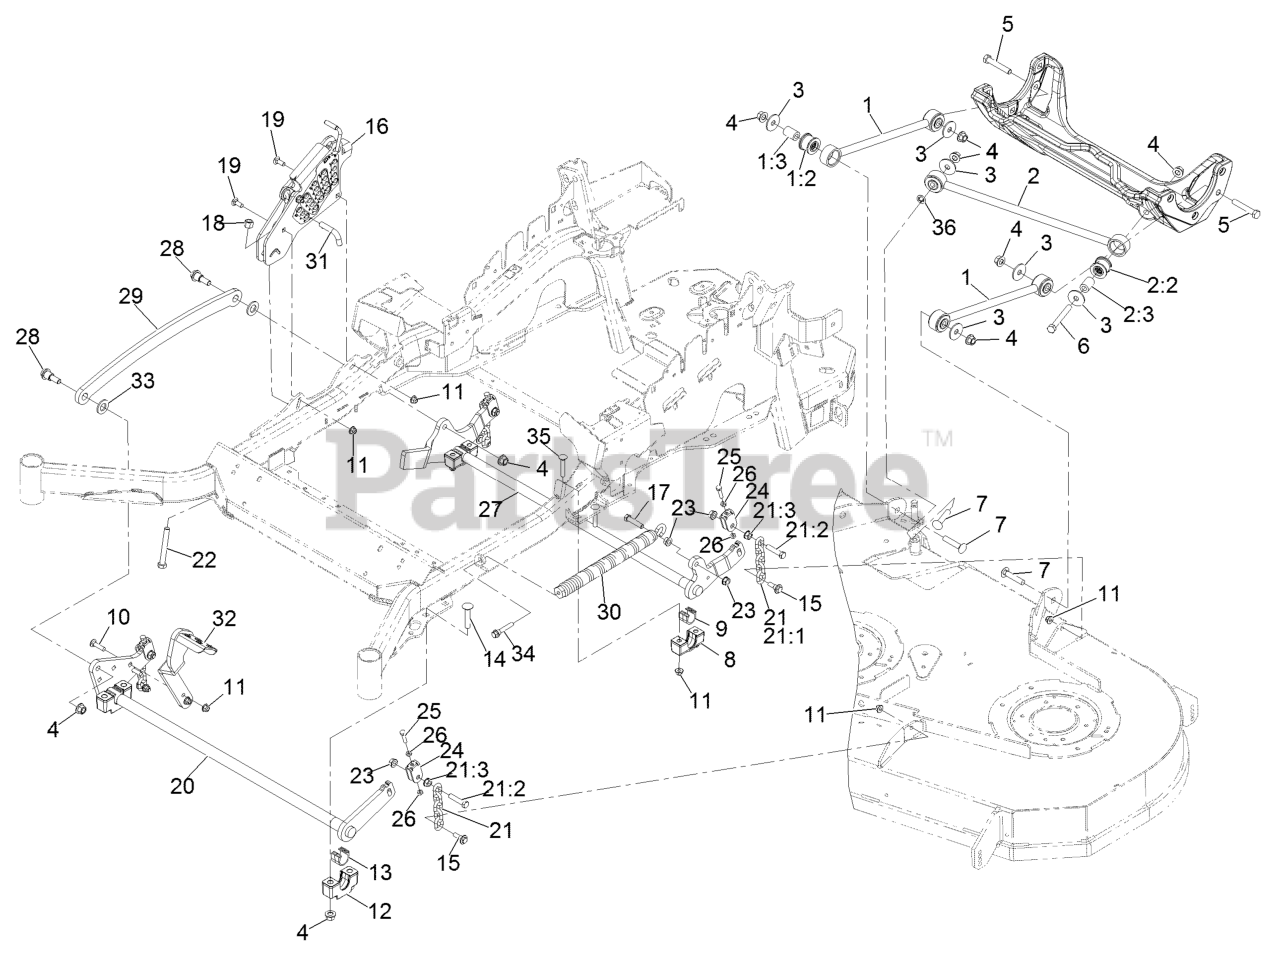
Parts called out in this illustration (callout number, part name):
1	DECK STRUT ASM
1:2	BUSHING-SUSPENSION, RUBBER
2	PANHARD ROD ASM
2:2	BUSHING-SUSPENSION, RUBBER
3	WASHER-THRUST
4	Nut-Lock 1/2-13
5	SCREW-HH
6	SCREW-HH
7	SCREW-CARR
8	SUPPORT-CROSS SHAFT, BEARING REAR
9	BEARING-CROSS SHAFT, REAR
10	SCREW-CARR
11	NUT-HF, NI
12	SUPPORT-CROSS SHAFT, BEARING
13	BEARING-CROSS SHAFT, FRON
14	Bolt-Carriage 1/2-13 X 2 1/2 Spl Neck
15	SCREW-SHOULDER, HHF
16	HOC ASM
17	SCREW-HH
18	NUT-LOCK, NI
19	BOLT-CARR
20	DECKLIFT-FRONT
21	DECK LIFT CHAIN ASM
21:1	CHAIN-LIFT, DECK
21:2	SCREW-HH
22	BOLT-TAP
24	YOKE-ADJUST, DECK
25	SCREW-HH
26	NUT-JAM
27	LIFT-DECK, REAR
28	SCREW-SHOULDER, HHF 1/2-13 X 1.12
29	LINK-LIFT, DECK
30	SPRING-EXTENSION
31	PIN-HOC
32	LEVER-FOOT
33	WASHER-FLAT
34	BOLT-SHOULDER
35	Bolt-Carriage 3/8-16 X 2 1/4
36	NUT-PUSH
